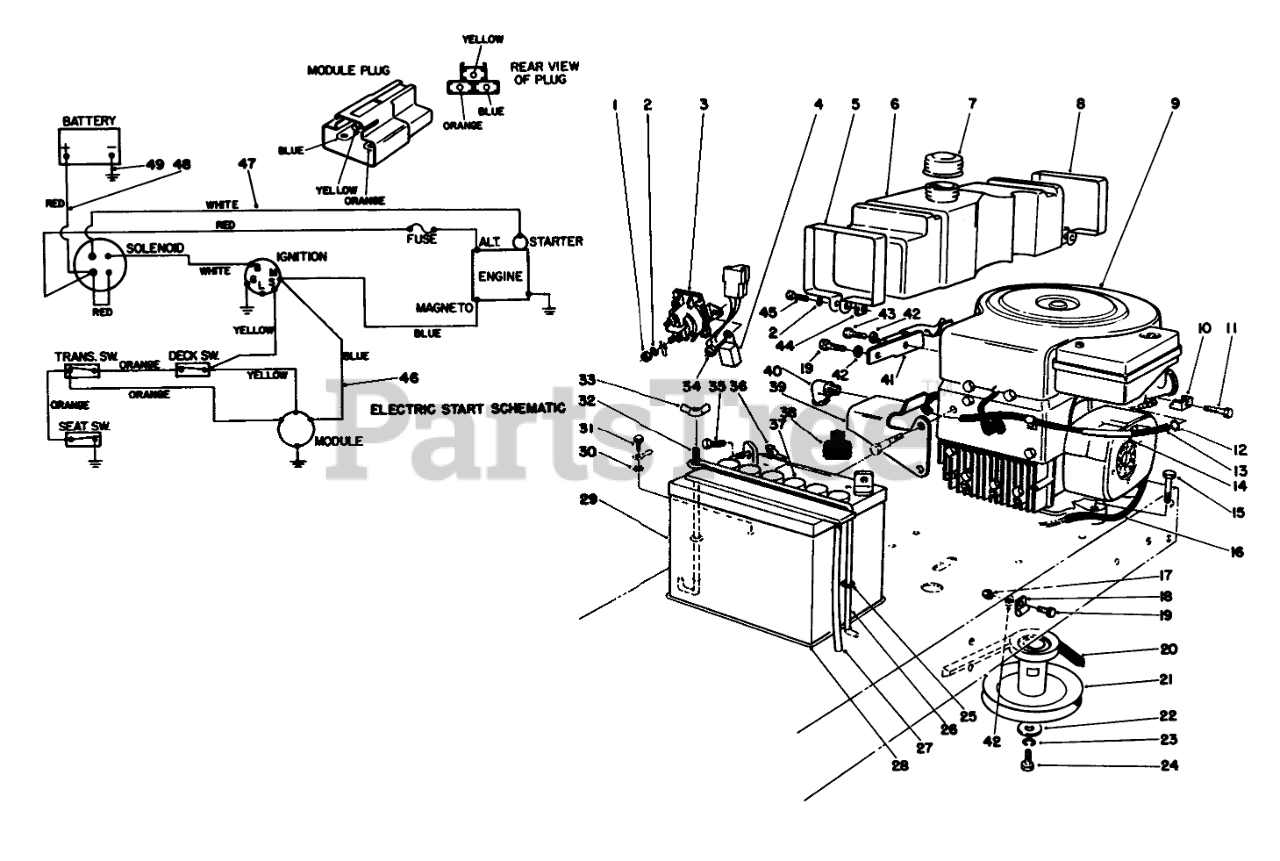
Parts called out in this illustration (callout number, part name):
1	NUT-JAM
2	WASHER-LOCK
3	SOLENOID
4	Module Interlock
5	Retainer-Front
6	TANK-5 QT GAS
7	GAS CAP ASM
8	Retainer-Tank Rear
9	Engine
10	CLAMP-CASING
11	SCREW W ENGINE
12	CLAMP-HOSE
13	HOSE-FUEL
14	SUPPORT-FUEL LINE
15	SCREW-HH
16	Cover-Protective
17	NUT-LOCK, NI
18	CLAMP
19	Screw
20	V-BELT, TRACTION
21	PULLEY
22	WASHER-FLAT
23	WASHER-LOCK
24	SCREW-HH
25	O-RING
26	HOLDDOWN-BATTERY
27	TUBE-BATT DRAIN/80-2600
28	Pad-Anti Skid
29	Battery
30	WASHER-LOCK, INTERNAL
31	SCREW-HHF
32	POST-BATTERY
33	NUT-WING
34	NUT-LOCK, CONE
35	SCREW-HH
36	NUT-WING
37	CAP-BATTERY
38	BOOT-TERMINAL
39	FRT TANK MTG BRKT B
40	ELBOW-STREET, 90 DEG
41	REAR TANK MTG BRKT B
42	WASHER-PLAIN
43	SCREW-HH
44	NUT-SQUARE
45	SCREW-HSH
46	Wire Harness
47	STARTER WIRE HARNESS
48	WIRE ASM
49	WIRE ASM(BATT/GRD.
